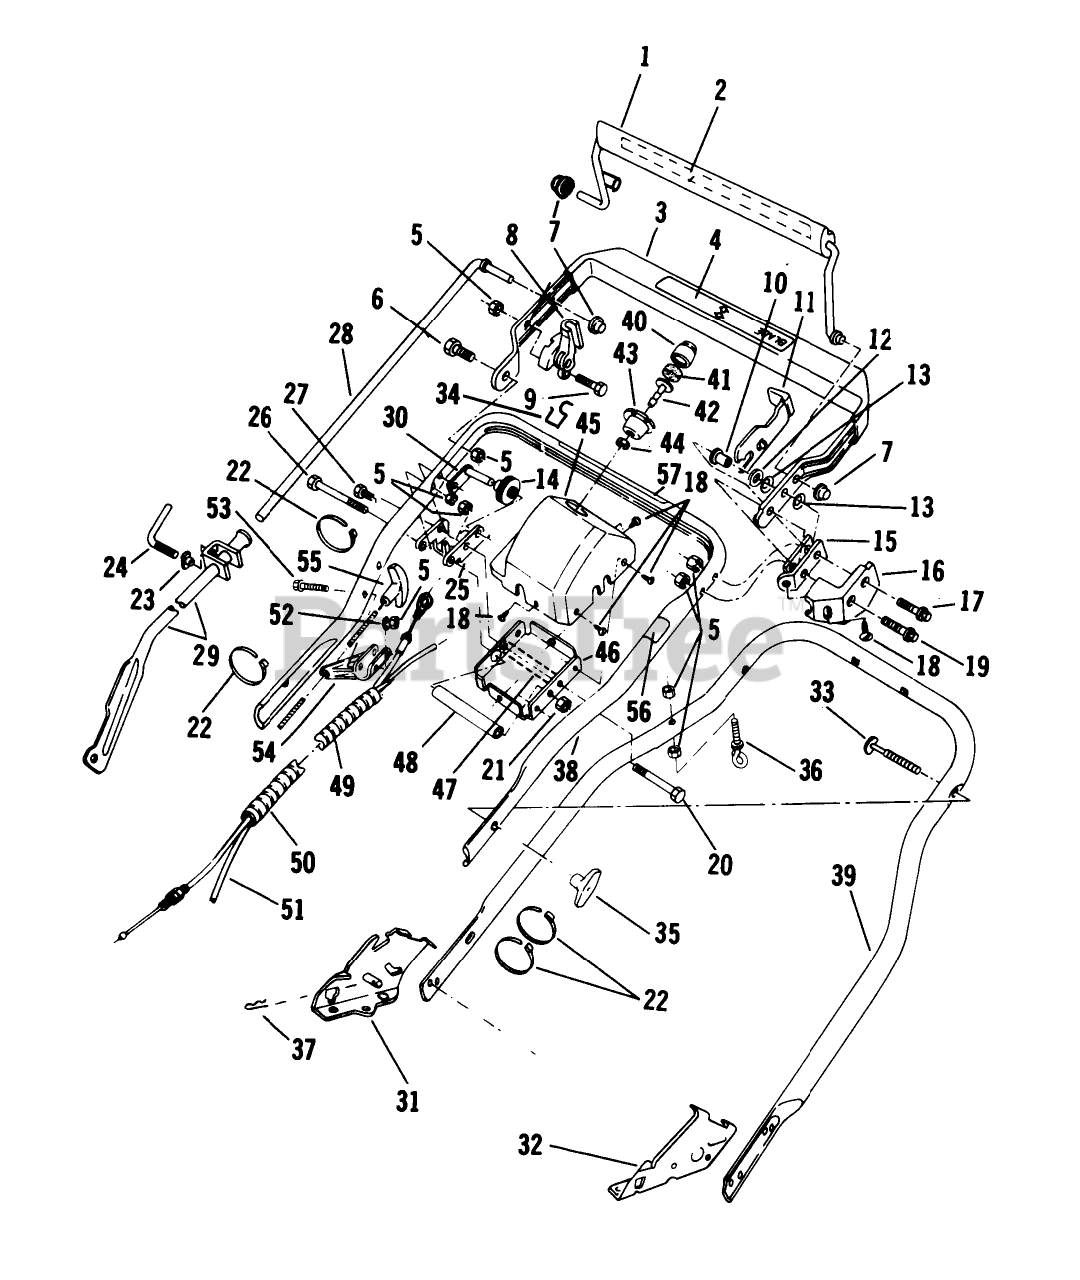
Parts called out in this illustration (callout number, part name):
5	LOCKNUT E
6	BOLT
10	SPACER
12	WASHER M
15	DOWN STOP
16	LOCKOUT GUARD
17	BOLT SHOU
18	SCREW F
19	SCREW
26	BOLT-CONSOLE
28	CONTROL ROD
33	BOLT QUALITY
35	NUT-WING
36	EYE BOLT WAS MFG
37	HAIR PIN
41	FILTER S
44	LOCKNUT S
47	SPACER
52	WASHER
55	HANDLE,STARTER
